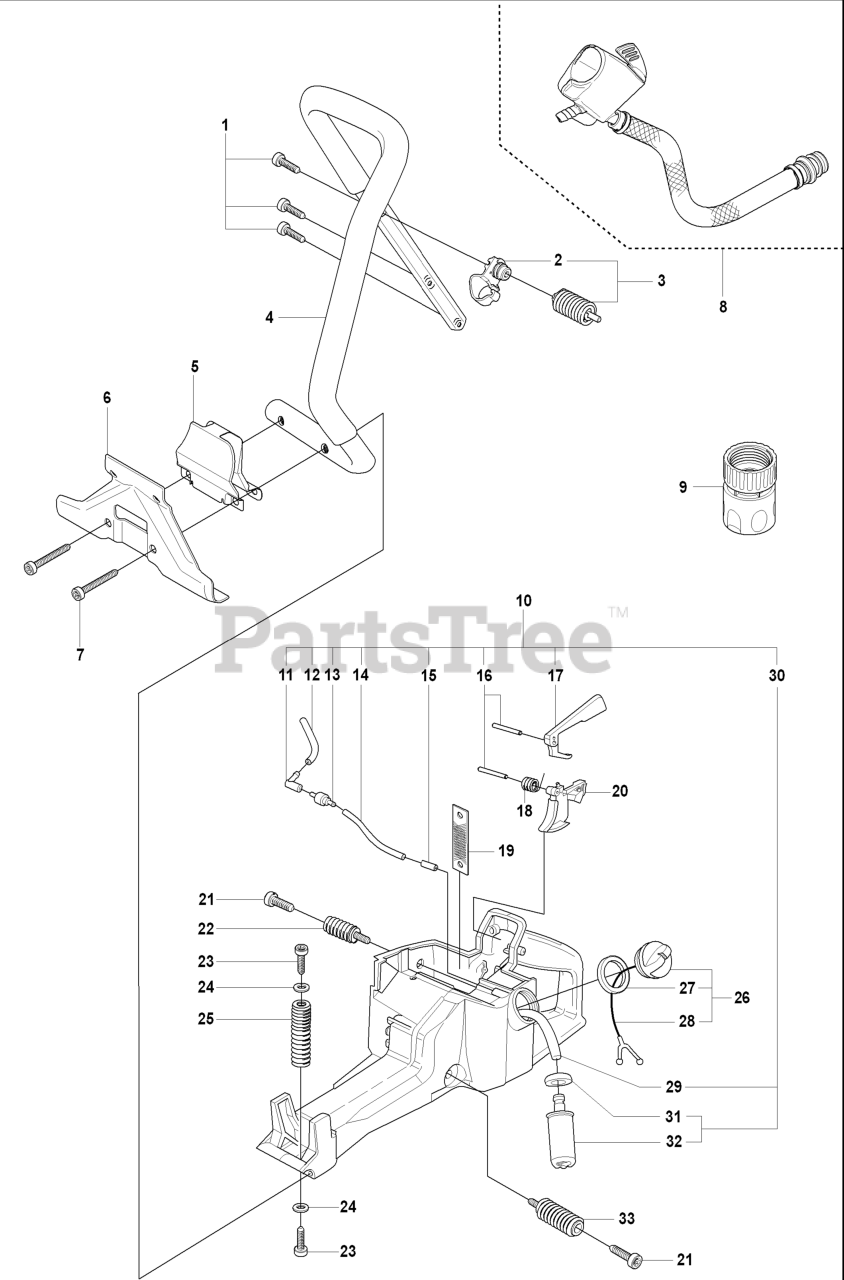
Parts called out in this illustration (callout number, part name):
2	SPRING RETAINER
3	%VIBRATION ABSORBER
5	PROTECTIVE PLATE
6	GROUND SUPPORT
8	RP HOSE
9	FEMALE QUICK COUPLER
10	FUEL TANK
12	HOSE
14	FUEL HOSE
16	PIN 3X25
17	THROTTLE LOCKOUT
20	THROTTLE TRIGGER
22	AV ELEMENT
24	WASHER 5.3X12
25	SPRING FRONT
26	TANK CAP ASSY
29	HOSE
30	FILTER
